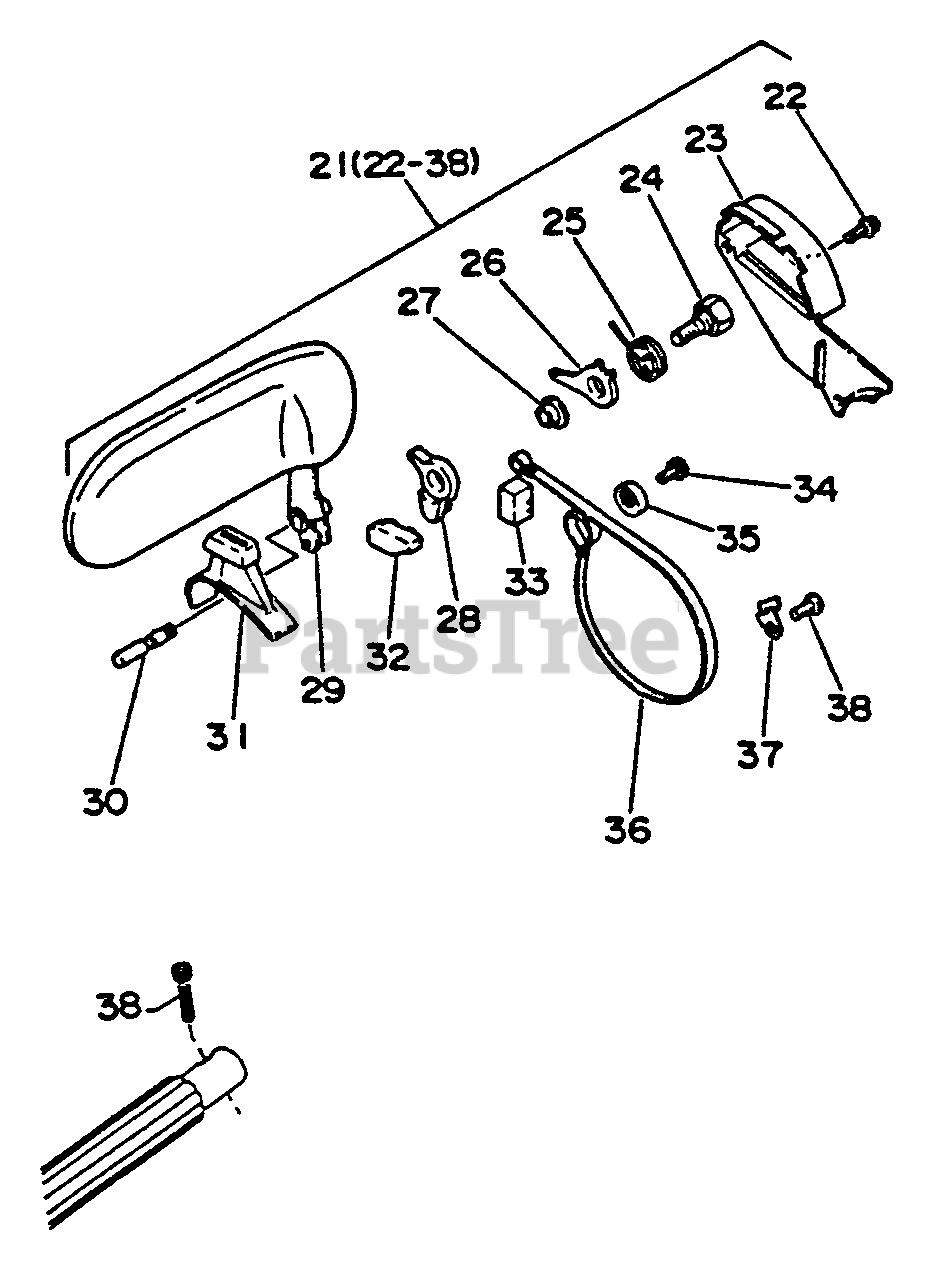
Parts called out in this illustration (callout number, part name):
21	CHAIN BRAKE ASSY
22	SCREW - 4X12
23	COVER, BRAKE
25	SPRING, RETURN
28	CONNECTOR
29	HANDLE
31	COVER, BRAKE
32	RESET, BRAKE
33	SEAL
34	SCREW - 5X10
35	ADJUSTER, BRAKE BAND
36	BAND, BRAKE
37	RETAINER, BRAKE BAND
38	SCREW - 5X25
